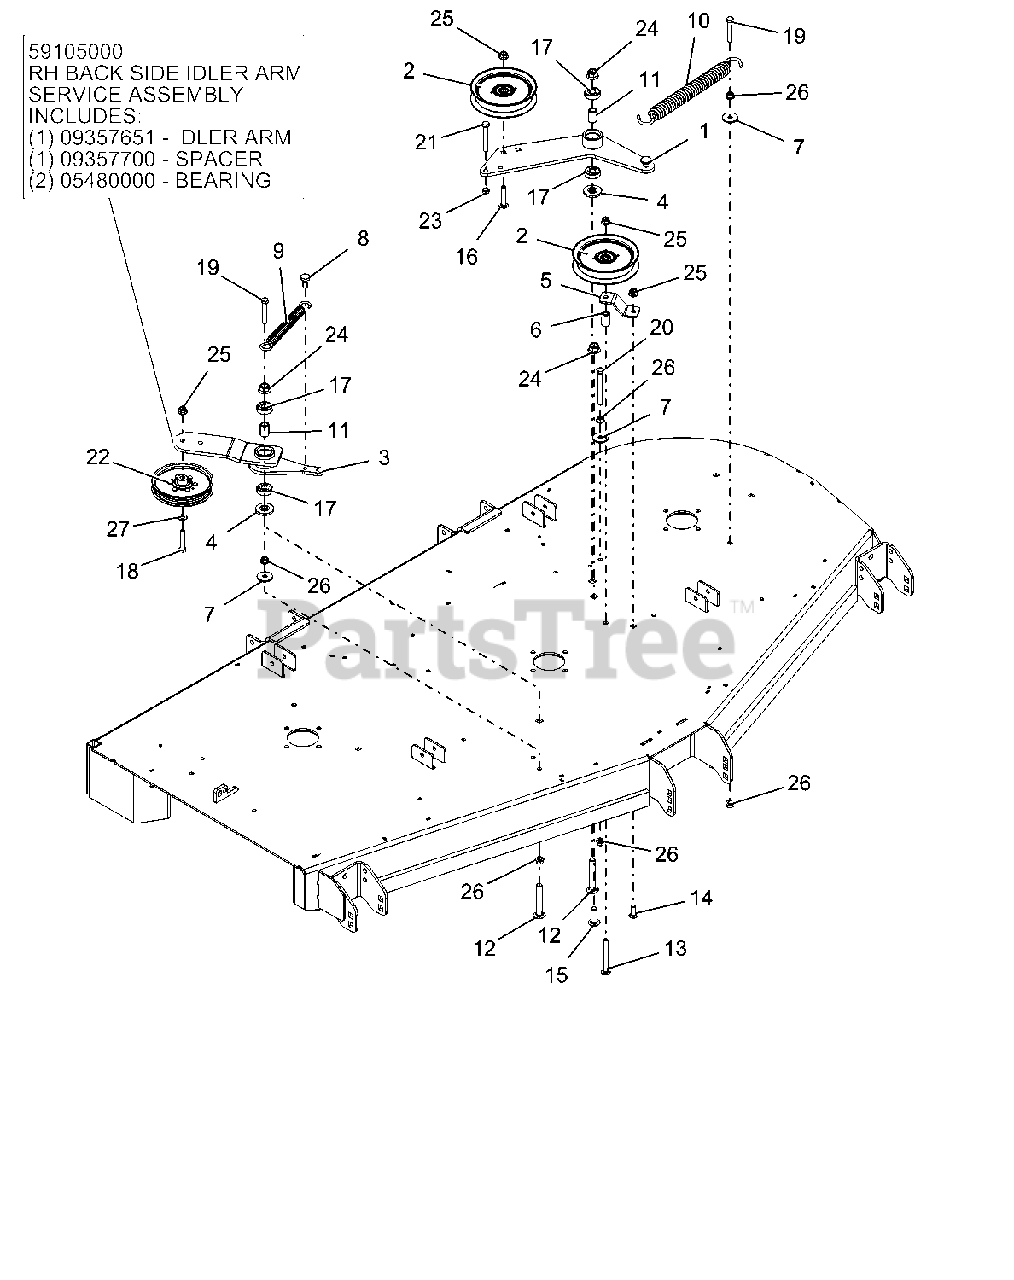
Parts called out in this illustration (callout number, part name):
1	WLDMT, DECK PTO IDLER ARM (BLACK)
2	IDLER, FLAT - 5.00" X .75"
3	WLDMT, DECK RH IDLER ARM
3	RH BACK SIDE IDLER ARM SERVICE ASSEMBLY
3	IDLER ARM
3	SPACER
3	BEARING
4	SPACER, IDLER ARM
5	BRKT, PTO FIXED IDLER MTG (RED)
6	BUSHING, SLV .380 X .750 X 1.190
7	WSHR-FL-STL .406X1.375X.135 YZ
8	BLT, SHLDR EP .38-16X.30 HEX YZ
9	SPRG, EXTENSION - SWIVEL
10	SPRG, EXTENSION
11	SPACER, .510 X .750 X 1.148
12	BLT-RDHDSQSHNK .50-13X3.25 YWZC
13	BLT-RHDSSQNK .38-16X3.50 G5YZ
14	BLT-RDHDSHSQNK.38-16X1.0 G5YZ
15	BLT-RDHDSQSHNK .50-13X1.50 YWZC
16	BLT-RHDSSQNK .38-16X2.00 G5YZ
17	BRG-BALL .500X1.375X.44
18	BLT-HEX .38-16X2.00 GR5 YWZC
19	BLT-HEX .38-16X2.25 GR5 YWZC
20	BLT-HEX .38-16X3.50 GR5 YWZC
21	BLT-HEX .38-16X2.75 GR5 YWZC
22	PULLEY, FLAT IDLER .500 X .375 W/BRG
23	NUT, JAM .375-16 YWZC
24	NUT-LK-NYL-FLG .50-13 YWZC
25	NUT-LK-NYL-FLG .38-16 YWZC
26	@NUT-SPNLK-FLG .375-16 YWZC
27	WSHR-FL-STL.406X.812X.065 YWZ
